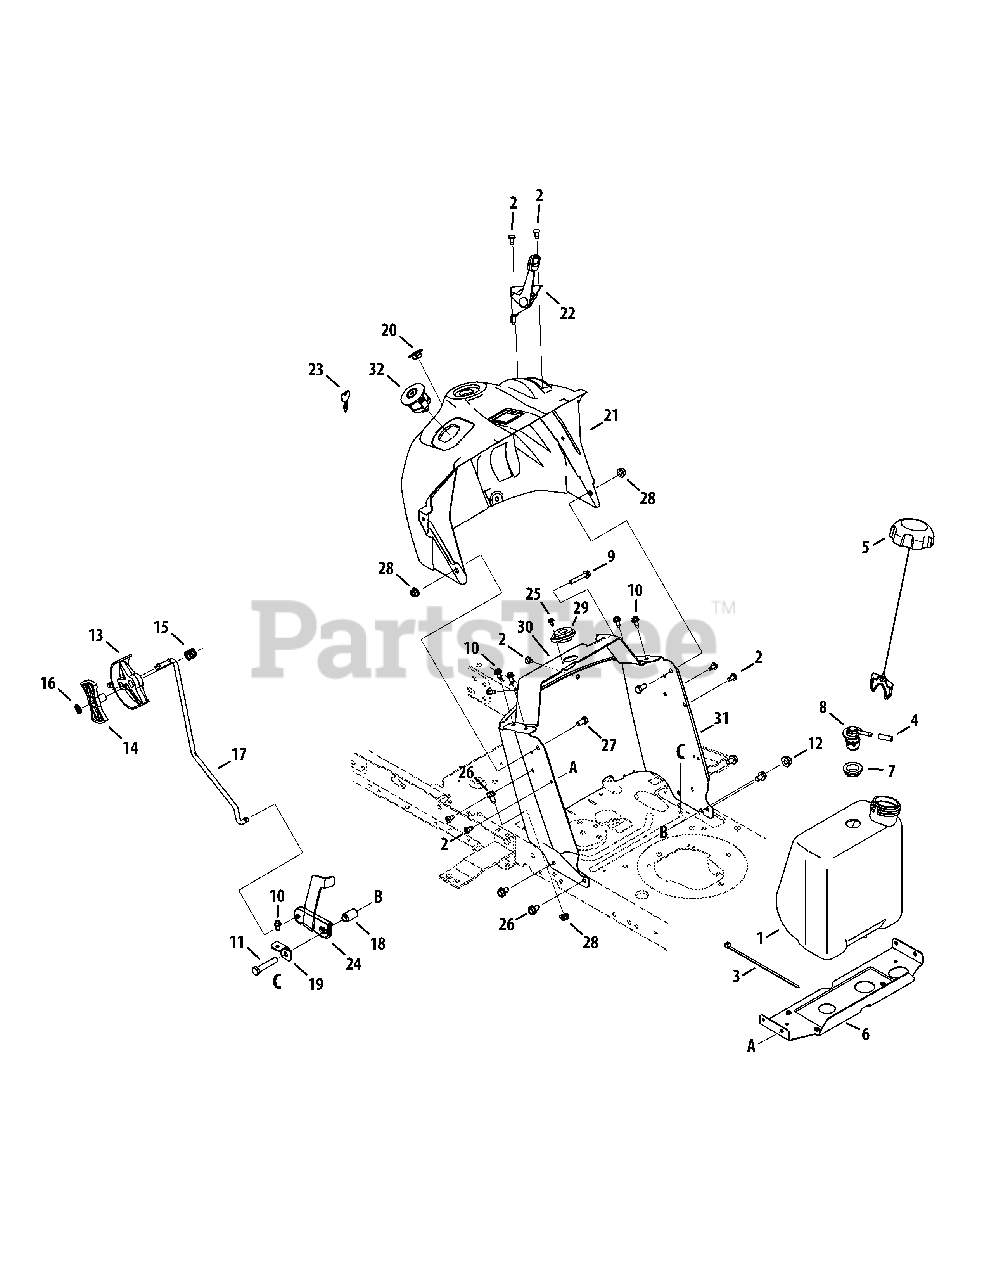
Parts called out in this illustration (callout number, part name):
1	Fuel Tank, 1.36 Gal.
2	Screw, Tap, 1/4-20, 0.500
3	Cable Tie, 36.0 Long
4	Hose Vent
5	Fuel Cap, 2.25"
6	Gas Tank Support Bracket
7	Rubber Grommet, 23 x 3.55
8	Rollover Valve
9	Hex Screw, 1/4-20 x 1.50
10	Tap Screw, 1/4-20, 0.625
11	Hex Screw, 3/8-16, 2.00, Gr5, Std
12	Flange Lock Nut, 3/8-16
13	Shift Lever
14	Index Control
15	Compr. Spring, .685 OD x .63
16	Lock Washer, 1/4
17	Speed Selector Control Rod
18	Flange Spacer, .390 X .671 X 1.095
19	Speed Latch
20	Choke Plug
21	Dash, Upper
22	Throttle/Choke Cable Assembly
23	Key, Assembly
24	Speed Latch - No RMC
25	Screw, #10-16 x .500
26	Tap Screw,5/16-18, 0.625
27	Hex Screw, 5/16-18 x .625
28	Flange Lock Nut, 5/16-18
29	Bearing, .628 ID x 1.36
30	Bracket, Steering Support
31	Dash, Lower No window
32	3 Position Key Switch
